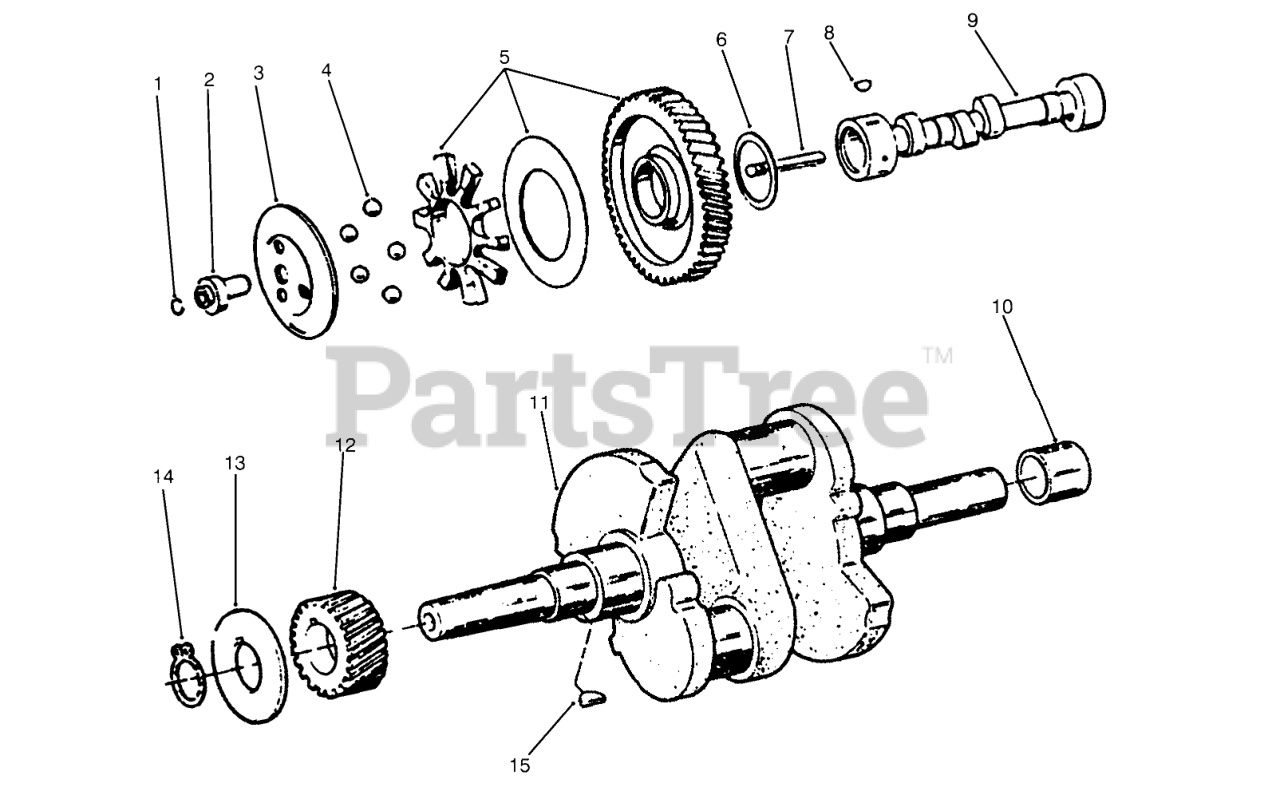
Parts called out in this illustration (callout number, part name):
2	HUB-GOVERNOR CUP
3	CUP-GOVERNOR
4	BEARING
5	Gear-Camshaft (Incl. Gear, Spacer, & Plate)
6	WASHER-THRUST
7	PIN-CENTER
9	Camshaft (Incl. Ref. #7)
10	BEARING SLEEVE
13	WASHER
